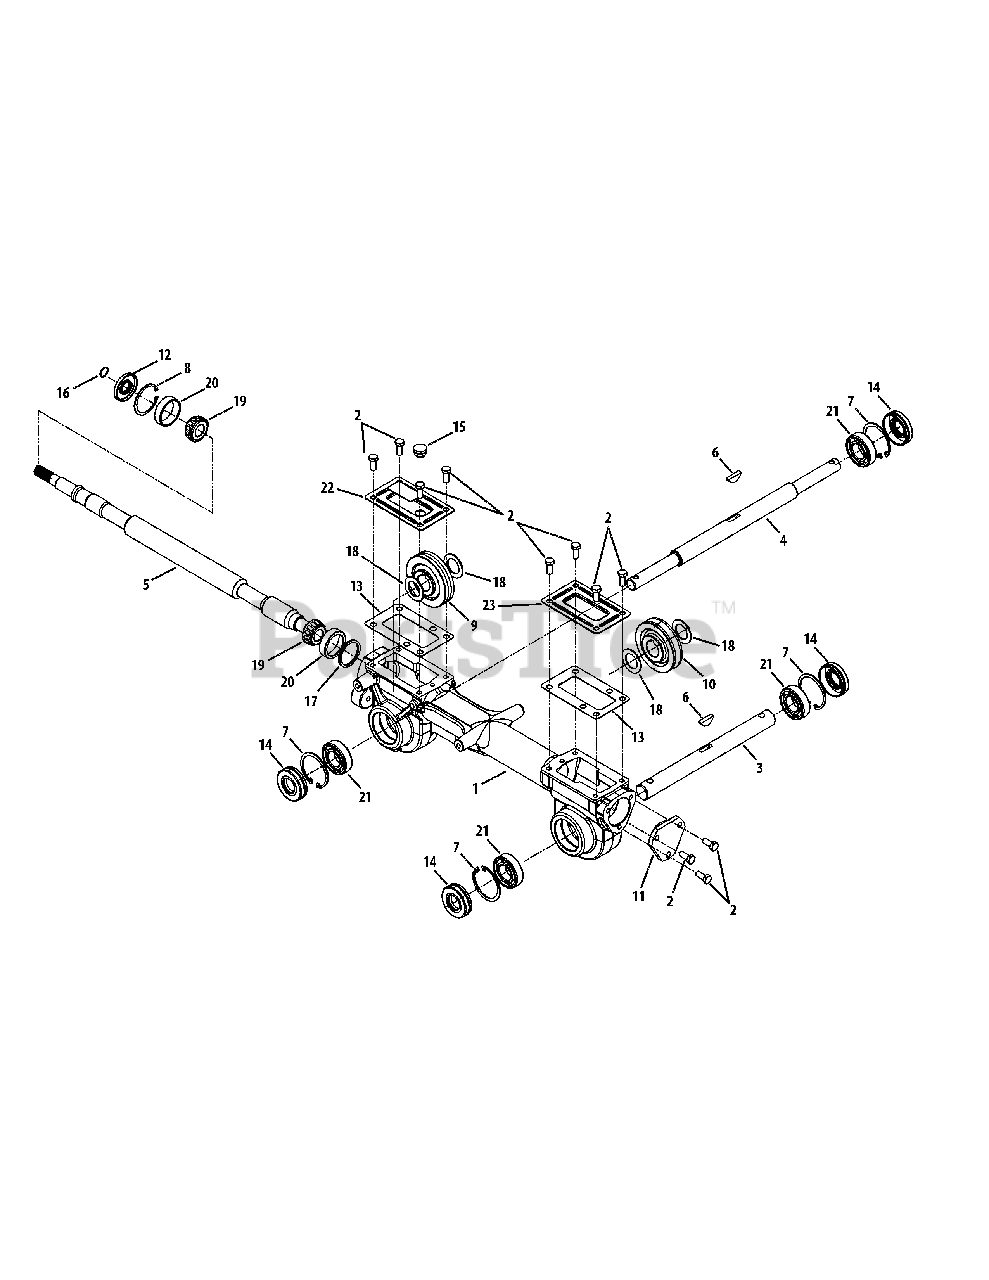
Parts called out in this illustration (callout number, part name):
1	Housing, Transmission
2	Hex Screw, 5/16-18, 75, Gr5
3	Shaft, Tiller
4	Shaft, Wheel
5	Shaft, Worm
6	Key, Hi Pro 25 x 1062
7	Retaining Ring
8	Retaining Ring, Int
9	Worm Gear, 61t, RH
10	Worm Gear, 30t, LH
11	Bearing Cover
12	Seal, Oil, 750 Shaft x 1783 Bore
13	Gasket, Gear Housing
14	Seal, Oil, 100 Shaft x 200 Bore
15	Rubber Plug, Oil
16	Wire Ring
17	Washer, Flat, 150 x 175 x 062
17	Washer, Flat, 150 x 175 x 005
17	Washer, Flat, 150 x 175 x 03
17	Washer, Flat, 150 x 175 x 010
18	Washer, Flat, 1010 x 156 x 060
19	Cone Bearing
20	Bearing Cup
21	Ball Bearing
22	Cover, Transmission
23	Cover, Transmission
